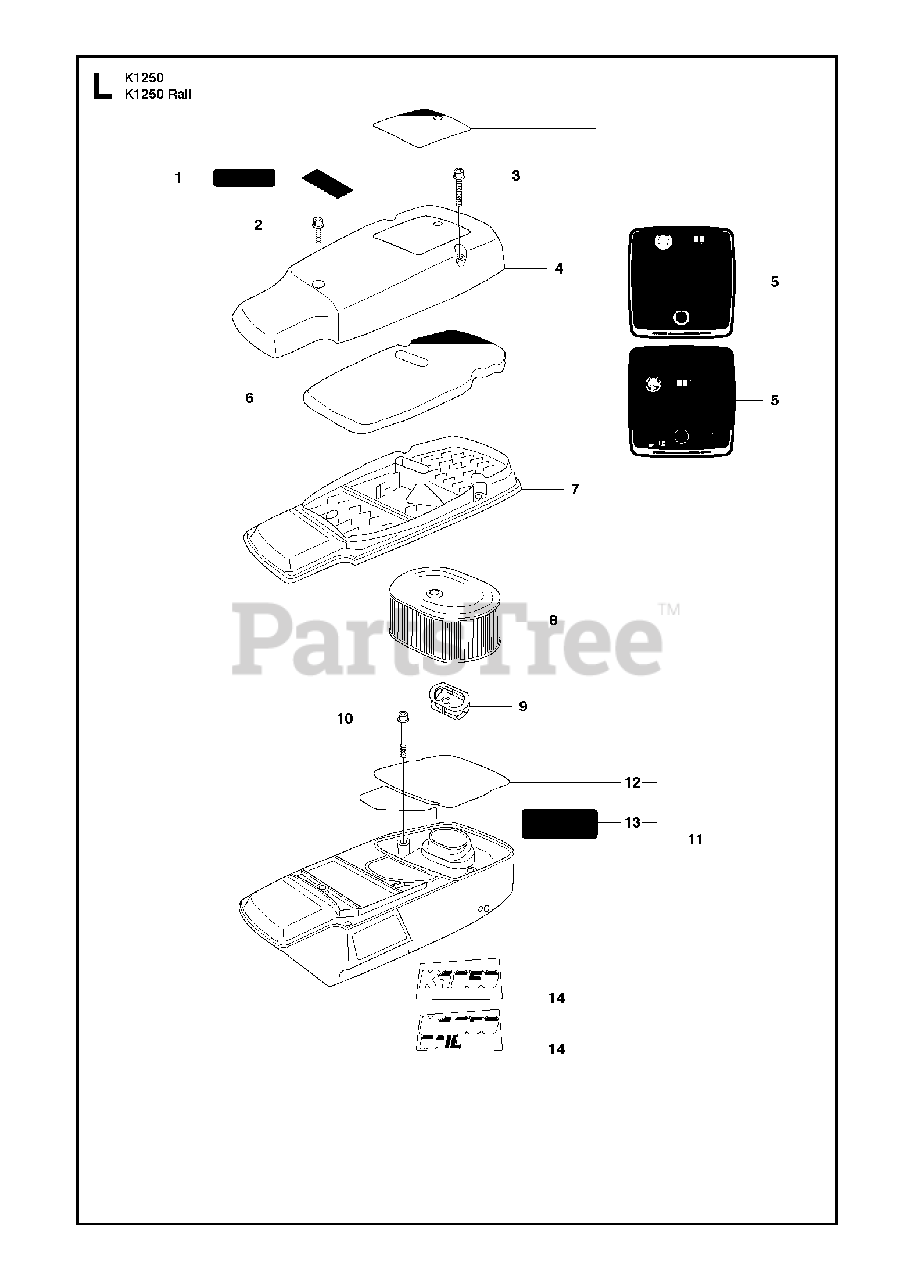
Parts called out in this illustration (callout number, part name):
2	SCREW CCRPANMO
3	SCREW CCRPANMO
4	FILTER COVER
7	FILTER BOTTOM
8	LUFTFILTER PAPPER
10	SCREW IHSCFM
11	CYLINDER COVERIncl. 12 - 13
